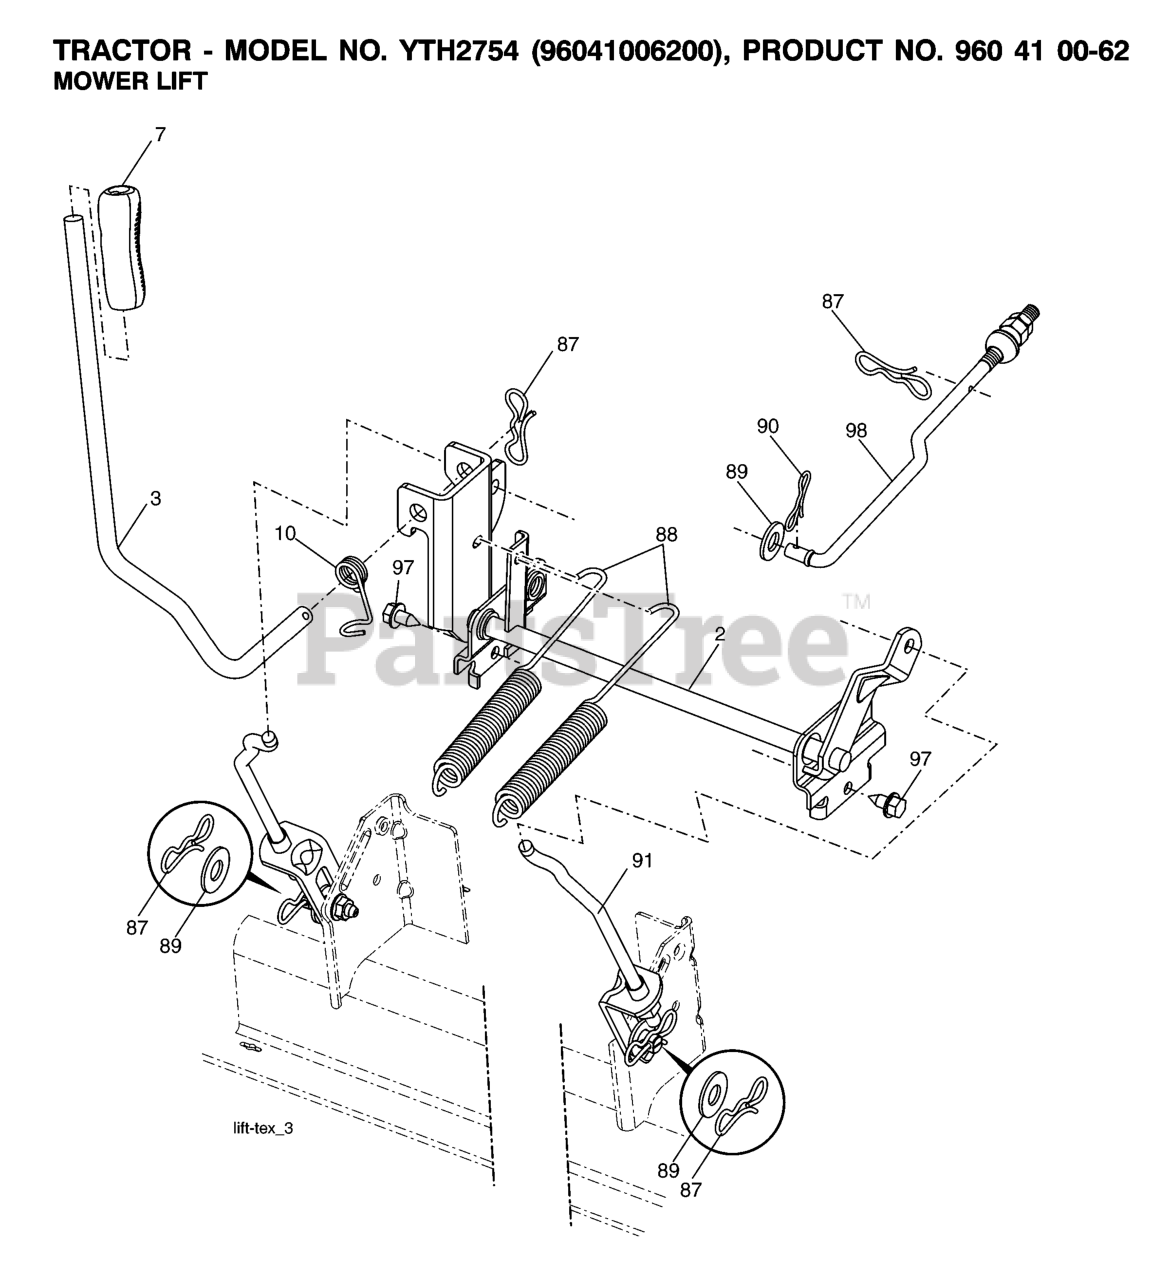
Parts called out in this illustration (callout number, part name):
2	SHAFT.ASM.LIFT.CROSS.H
3	LEVER.LIFT.HANDLE.GT
7	GRIP.HANDLE.LIFT.PVC.BLACK
10	SPRING.TORSION.LIFT.HANDLE
87	PIN.COTTER.7/16.BOW TI.
88	SPRING.LIFT.ASSIST.GT2
89	WASHER.CLEAR.ZINC
90	PIN.COTTER.5/16.BOW TI
91	LINK.ASM.LIFT.54"TG
97	SCREW 3/8-16X3/4
98	LINK.ASM.SUSP.FRONT.MWR.10.5
